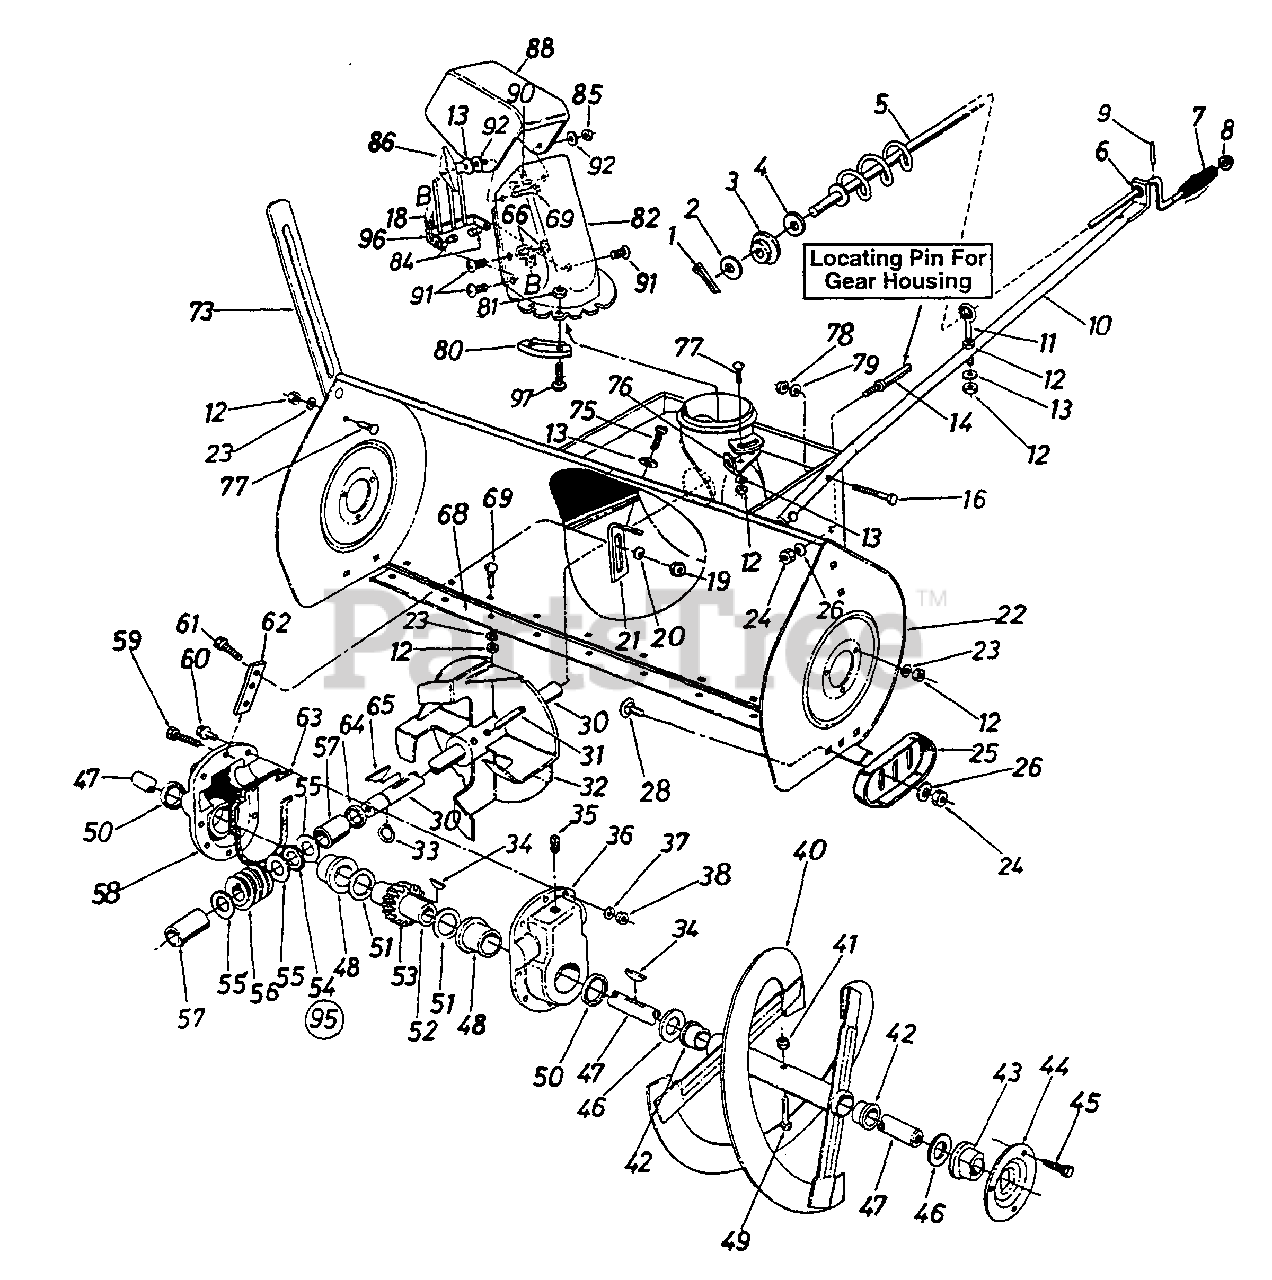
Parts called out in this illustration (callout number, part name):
1	Cotter Pin 3/32" x .75"
2	Fl-Wash. .385" I.D. x .62" O.D. x .06"
3	Plastic Bushing .380" I.D.
4	Fl-Wash. .385" I.D. x .62" O.D. x .06"
5	Chute Crank Ass'y.
6	Plastic Bushing .38" I.D.
7	Knob - Black
8	Cap Speed Nut 3/8" Rod
9	Spring Pin
10	Chute Crank Supporting Tube
11	Eyebolt Chute Crank Support
12	Hex Nut 5/16-18 Thd.
13	Bell-Wash. .345" I.D. x .88" O.D. x .06"
14	Belt Keeper Studs 3/8-16 x 2.75"
16	Hex Bolt 3/8-24 x 1.25" Lg.
18	Extension Spring
19	Hex Nut 1/4-28 Thd.
20	Bell-Wash. .25" I.D. x .88" O.D. x .062"
22	45" Snow Thrower Hsg. Ass'y.
23	L-Wash. 5/16" I.D.
24	Hex Jam Nut 3/8-16 Thd.
25	Reversible Slide Shoe
26	Bell-Wash. .4" I.D. x .88" O.D. x .06"
28	Carr. Bolt 3/8-16 x .62" Lg.
30	Blower Axle 14.75" Lg.
31	Spr. Spiral Pin - H.D.
34	#91 Woodruff Key 1/4" x 3/4" Dia.
35	Plastic Vented Plug 1/4-18 Pipe Thd.
36	Gear Hsg. Half - L.H.
37	Shakeproof Spr. Wash.
38	Hex Ins. L-Nut 5/16-18 Thd.
41	Hex Ins. L-Nut 5/16-18 Thd.
42	Flange Bearing
43	Flange Bearing w/Flats
44	Bearing Housing
45	Hex Sems Bolt 5/16-18 x .75" Lg.
46	Fl-Wash.
47	Spiral Axle
48	Flange Bearing
49	Shear Bolt 5/16-18 x 1.75
50	Oil Seal 1.5" I.D. Garlock
51	Fl-Wash. 1.5" I.D. x 2" O.D. x .03"
52	Worm Gear Shaft
53	Worm Wheel - L.H. Double Thd.
54	Thrust Brg. .88" I.D. x 1.44" O.D. x .078"
55	Fl-Wash. .88" I.D. x 1.4" O.D. x .125"
56	Worm Gear - L.H. Double Thd.
57	Sleeve Brg. .875" I.D.
58	Gear Hsg. Half - R.H.
59	Hex Bolt 5/16-18 x 1.25" Lg.
60	Hex Bolt 5/16 x 1" Lg.
61	Hex Bolt 1/4-28 x .75" Lg.
62	Gear Hsg. Support Plate
63	Rubber Gasket
64	Oil Seal for .875" I.D. Garlock
65	#9 Hi-Pro Key 3/16" x 3/4 Dia. - H.T.
66	Hex L-Nut 1/4-20 Thd.
69	Carr-Bolt 5/16-18 x 1" Lg.
75	Hex AB-Tap Scr. 5/16 x .75" Lg.
77	Carr. Bolt 5/16-18 x .75" Lg.
78	Hex Nut 3/8-24 Thd.
79	L-Wash. 3/8" I.D.
80	Chute Flange Keeper
81	Hex Flange L-Nut 1/4-20 Thd.
82	Lower Chute
84	Shld. Nut 1/4-20 Thd.
85	Hex L-Nut 5/16-18 Thd.
86	Hand Knob
88	Upper Chute
90	Truss Mach. Scr. 5/16-18 x .75" Lg.
91	Truss Mach. Scr. 1/4-20 x .5" Lg.
92	Fl-Wash. .344" I.D. x 1.125 O.D. x .125"
95	Gear Box Ass'y. Complete
96	Truss Mach. Scr. 1/4-20 x 3/4" Lg.
97	Hex Bolt 1/4-20 x .75" Lg.
